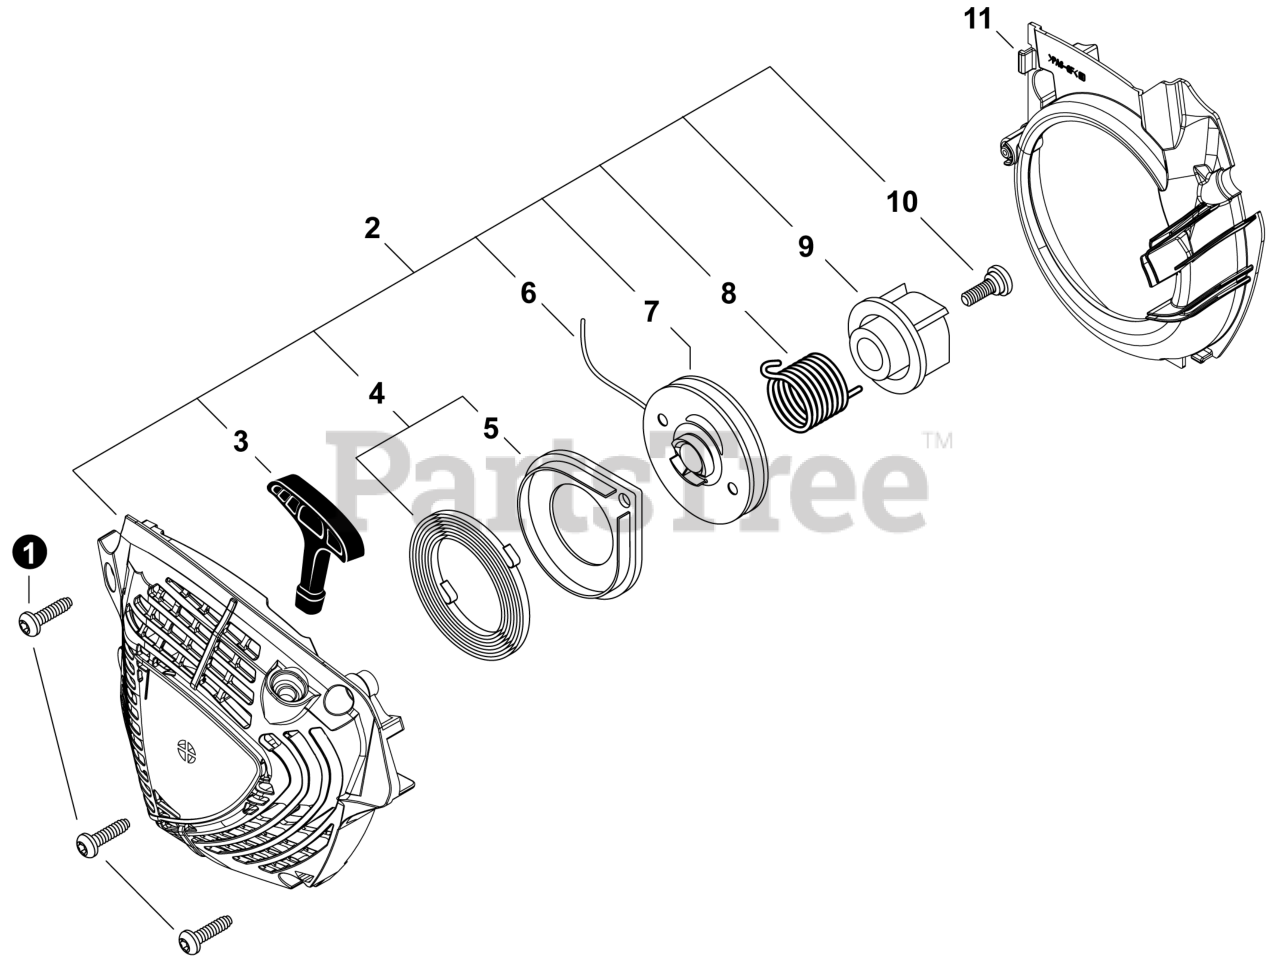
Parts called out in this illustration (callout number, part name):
1	BOLT, TORX 5x20
2	STARTER ASSY, RECOIL
3	GRIP, STARTER
4	SPRING KIT, RECOIL
5	SPRING CASE
6	ROPE, STARTER 3.5x900
7	REEL, ROPE
8	SPRING, TORSION
9	PAWL CATCHER
10	SCREW 5
11	COVER, FAN
